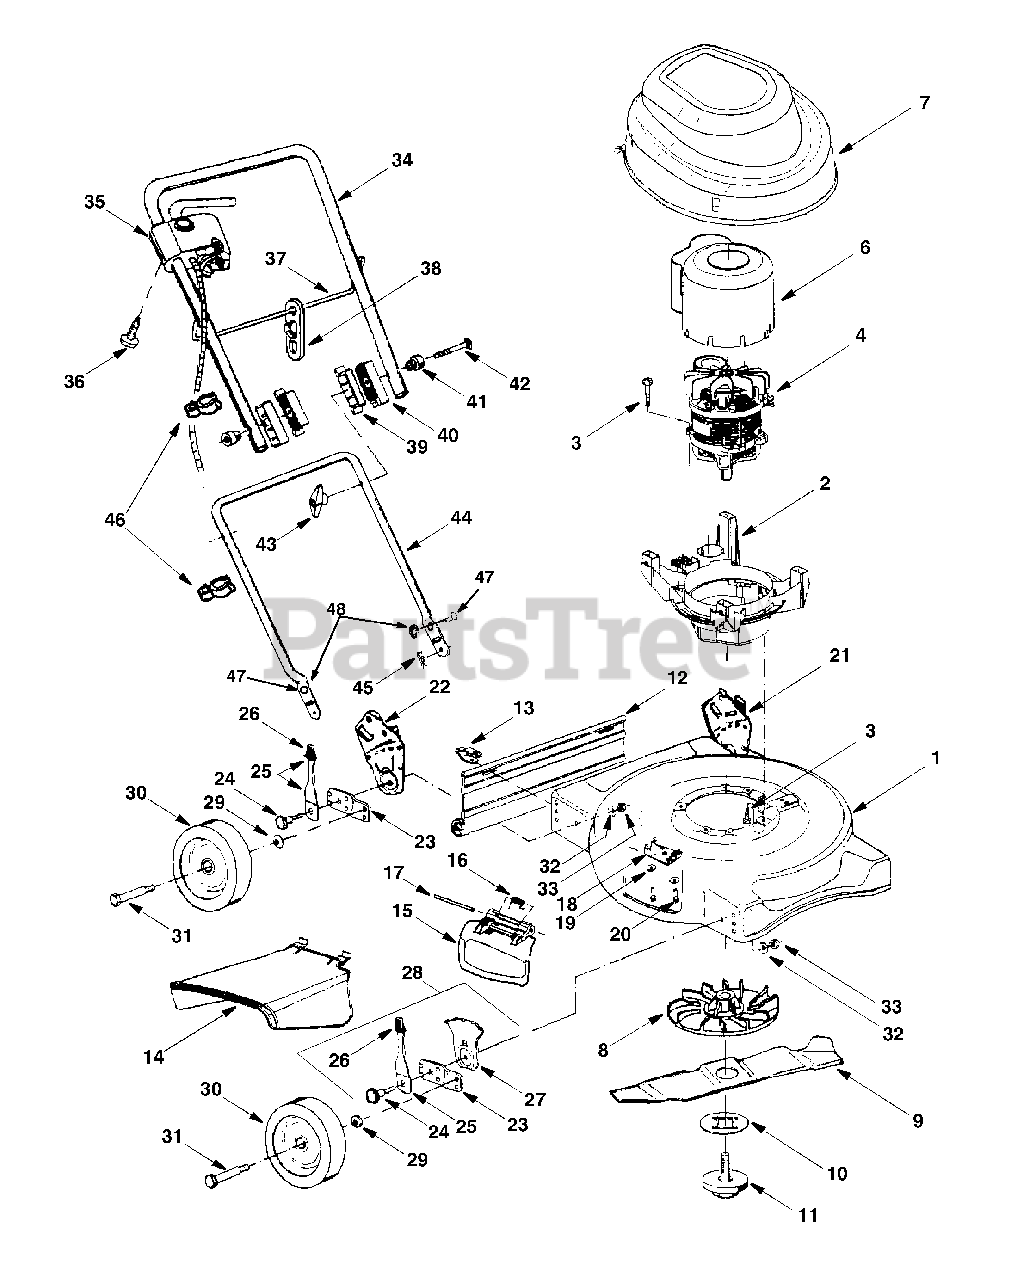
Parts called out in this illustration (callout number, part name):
3	Screw
4	Electric Motor, 115V, 1500W
6	Air Guide Cover
9	Mulching Blade
10	Locking Plate
11	Screw, Blade
12	Trailing Shield
13	Hinge Clip
14	Side Discharge Deflector
15	Mulch Plug
16	Torsion Spring
17	Hinge Pin
19	Beleville Washer
20	Screw
21	Handle Bracket Assy. LH
22	Handle Bracket Assy. RH
24	Shoulder Bolt
25	Lever and Knob Assy.
26	Knob, Height Adjustment
27	Adjusting Plate
28	Height Adjustment Assembly RH
29	Spring Washer
30	Wheel
31	Axle Bolt
32	Spring Washer
36	Screw
37	Guide Rod
39	Height Adjuster, Lower Handle
40	Height Adjuster, Upper Handle
41	Insulating Washer
42	Carriage Bolt
43	Wing Nut
46	Cable Guide
47	Mach. Screw 1/4-20 x .75"
48	Wing Nut
